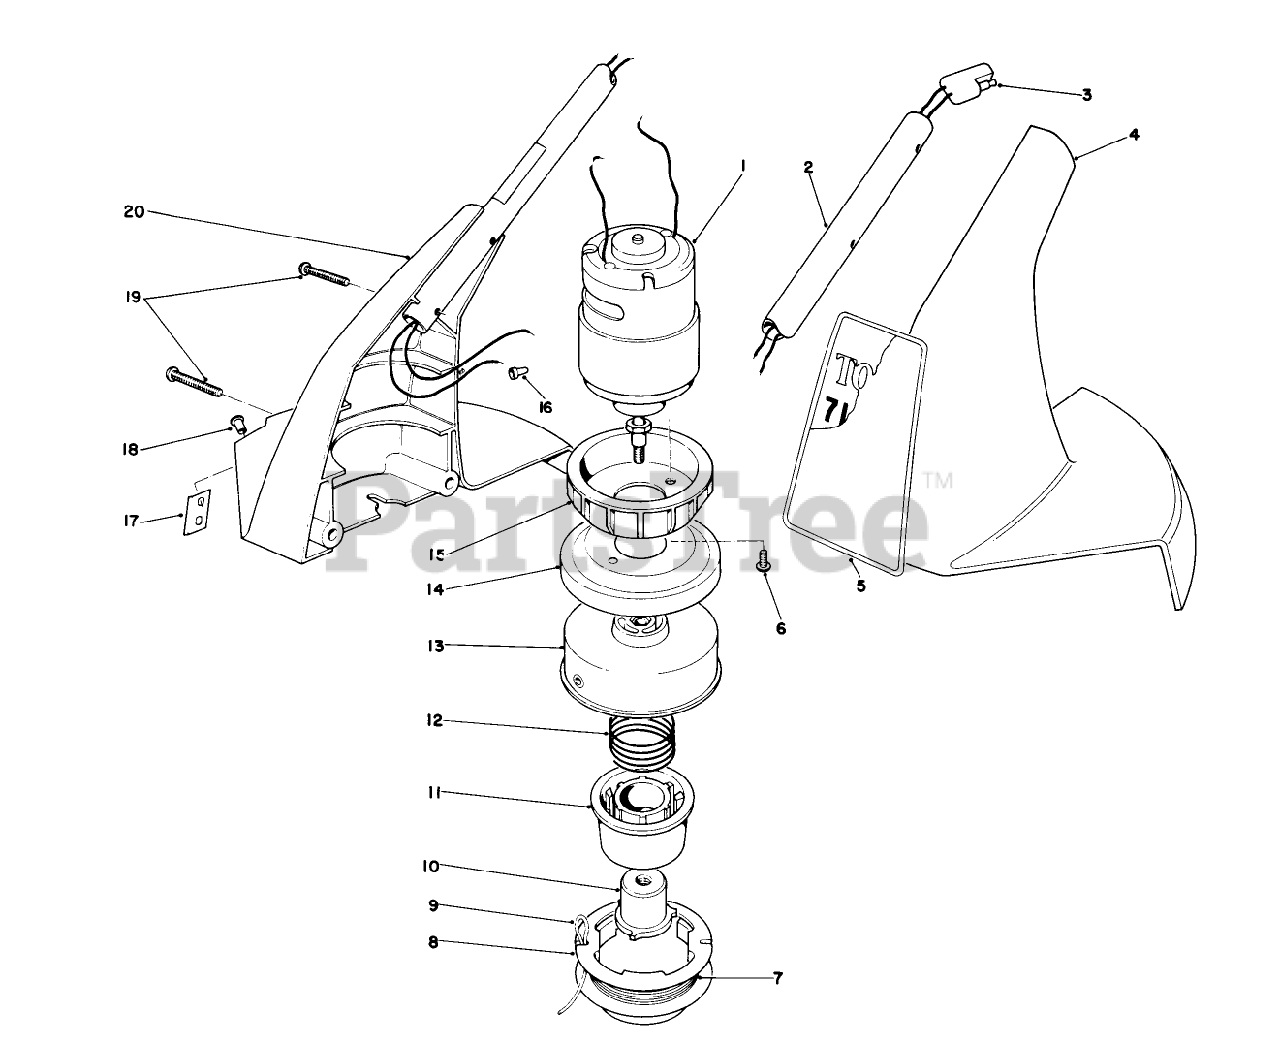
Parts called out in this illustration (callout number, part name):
7	Cutting Line (12- .05 Dia.)
8	CAP-SPOOL
9	Line-Cutting (30- .05 Dia.)
10	DRIVER
11	CORE - SPOOL
16	CONNECTOR SCREW
17	Blade-Knife
18	Rivet
19	SCREW-PLASTITE
